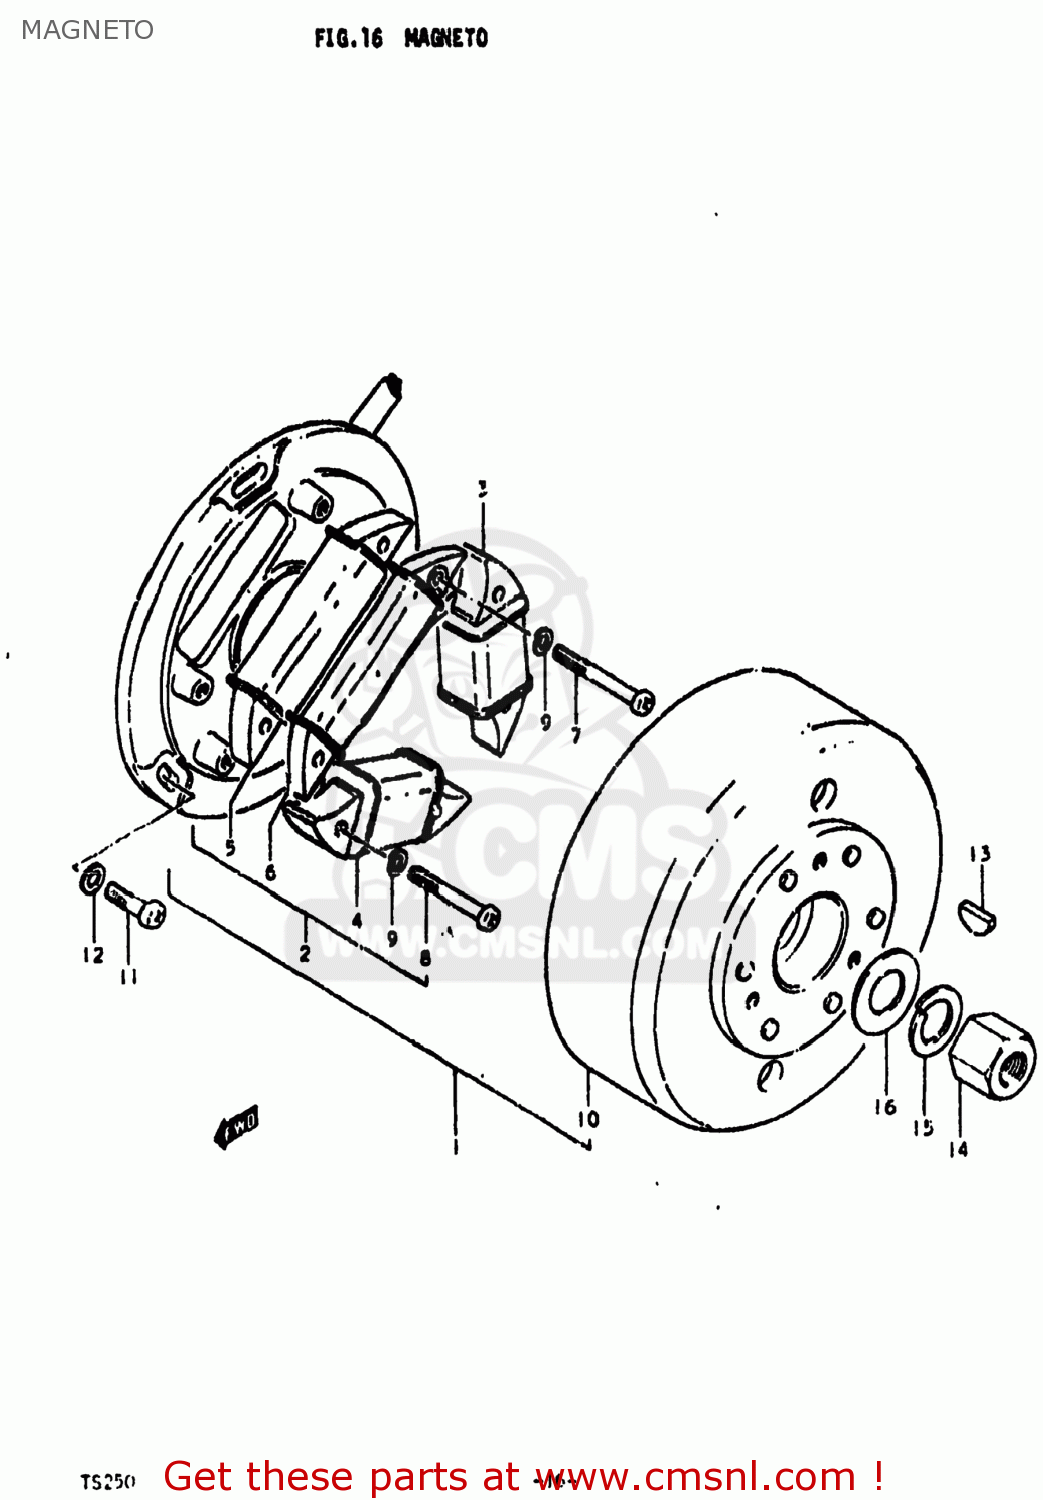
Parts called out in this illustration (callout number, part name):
1	MAGNETO ASSEMBLY
2	STATOR ASSEMBLY
3	COIL,CHARGE
4	COIL
5	COIL
6	COIL,PULSER
7	SCREW 5X35
8	SCREW
9	LOCK WASHER
10	ROTOR ASSEMBLY
11	SCREW
12	WASHER
13	KEY 4MM
14	NUT
15	LOCK WASHER
16	WASHER(14X27X3)
